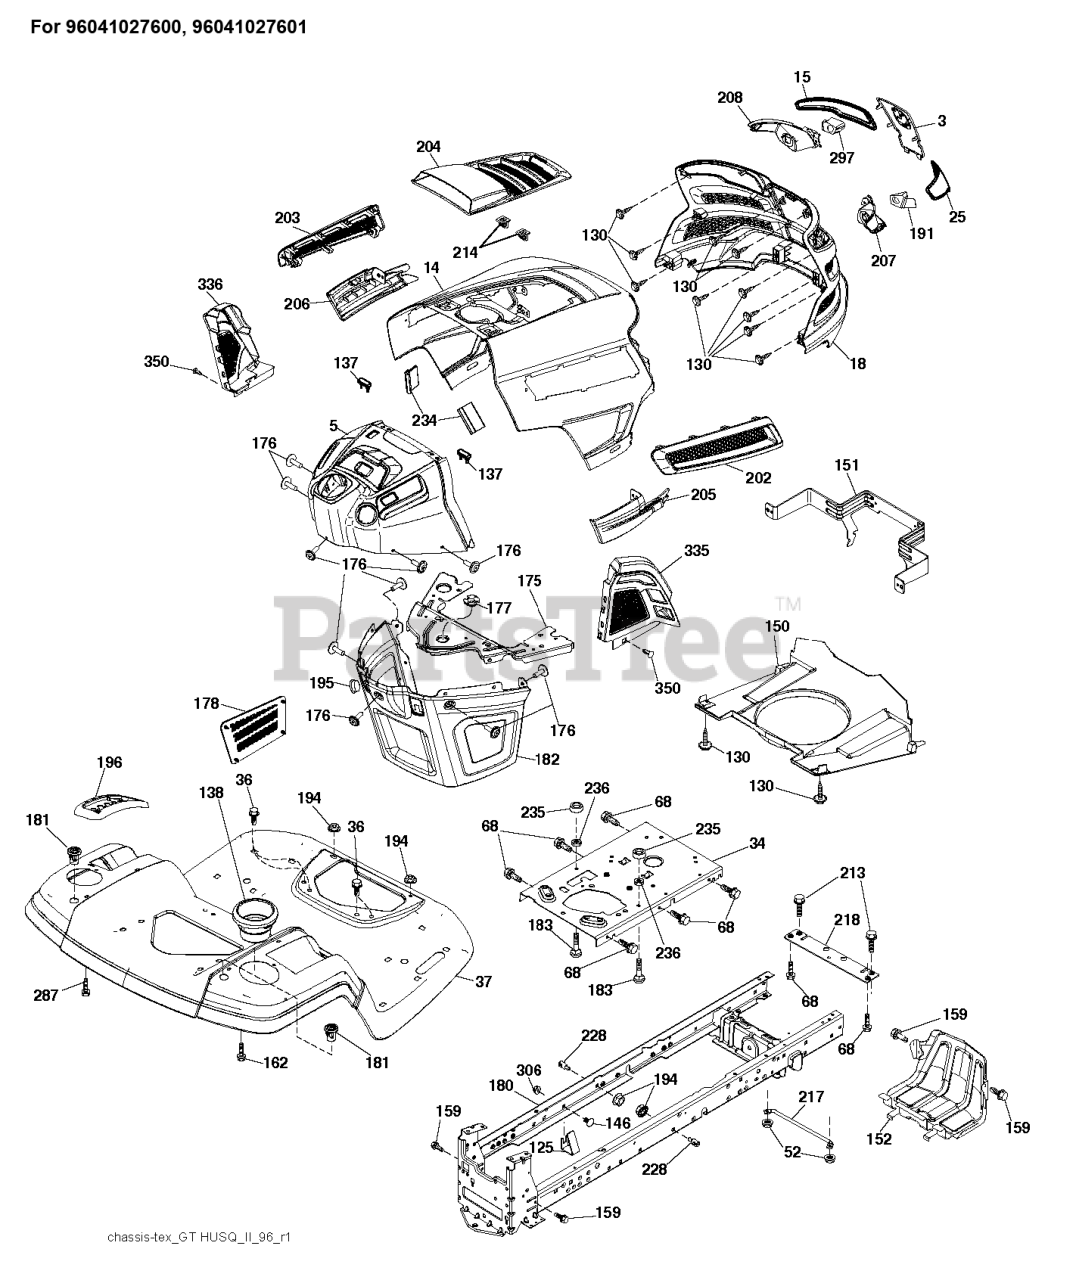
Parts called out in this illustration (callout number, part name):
3	APPLIQUE.SUBASM.GT.HUSQ.II
5	DASHBOARD.UPPER.ASM.GT2.X498
5	RP.DASH.UPP.GT2.SM.MC.CHOKE
14	HOOD.ASM.HUSQVARNA.GT.TEX.ORAN
15	LENS.HEADLIGHT.LH.GTII.2011
25	LENS.HEADLIGHT.RH.GTII.2011
34	PLATE.ENGINE.WELDED.CHASSIS
36	SCREW 5/16"
37	FENDER.TLT.PDL.CNTRL.W/CPH.ORG
52	LOCKNUT
125	CLIP.FUEL.LINE
130	SCREW.#10 X 0.750.BOS
137	BUMPER DASH
138	HOLDER.CUP.LT.GREY
146	BOLT.RDHD.SHT.SQNK.3/8-16X5/8
150	AIR DUCT.GTV2(1.66"RING HEIGHT
151	BRACKET.PIVOT.HOOD.GT.HUSQ.II
152	SHIELD.BROWNING.PNT.GT.V2
159	SCREW, 3/8-16X3/4
162	SCREW.HI-LO.CONSOLE
175	PLATE.PNT.CROSSMEMBER.HUSQ/PRE
176	SCREW.#10-24X5/8.RN.QU
177	BUSHING, STEERING
178	CARGO.ASM.NET.TXGT.W/C
180	CHASSIS
181	BUSHING.MNT.FEND.CRGO.
182	DASH.LOWER.COMMON.12V.ADAPTOR
183	BOLT.5/16-18X1-1/4 FULL THD
191	INSERT.REFLECTIVE.RH.HUSQ.GTII
194	NUT LOCK HEX FLANGE 5/16-18
195	PLUG.HOLE.DASH.LOWER.12V.BLK
196	DECKLFT.CONSOL FULL ASSM GREY
202	VENT.SIDE.RH.GT.HUSQ.II.
203	VENT.SIDE.LH.GT.HUSQ.II.498
204	VENT.TOP.HUSQ.GT2
205	SIDE.TRIM.RH.GT.HUSQ.II
206	SIDE.TRIM.LH.GT.HUSQ.II.GRAY
207	HEADLIGHT.CUP.BEZEL.HUS.GT2.RH
208	HEADLIGHT.CUP.BEZEL.HUS.GT2.LH
213	SCREW HEXAGON HEAD SCREW 5/16-
214	CLIP.RETAINER.TINNER.
217	ROD.PIVOT.HOOD
218	X-PIECE.HOOD.STOP.NON/
228	STUD.FASTNER.W/ANTI-ROTATE
234	BUMPER.HOOD.TEX.HUSQVARNA
235	SPACER FENDER
236	NUT.CENTERLOCK.5/16-
287	SCREW 1/4X20
297	INSERT.REFLECTIVE.LH.HUSQ.GTII
306	NUT LOCK FLG 3/8-16 UNC
335	COVER.LOWER.DASH.RH.BLACK
336	COVER-LH.LOWER.DASH.GT2.BLACK
350	CLIP.X-MAS.TREE
